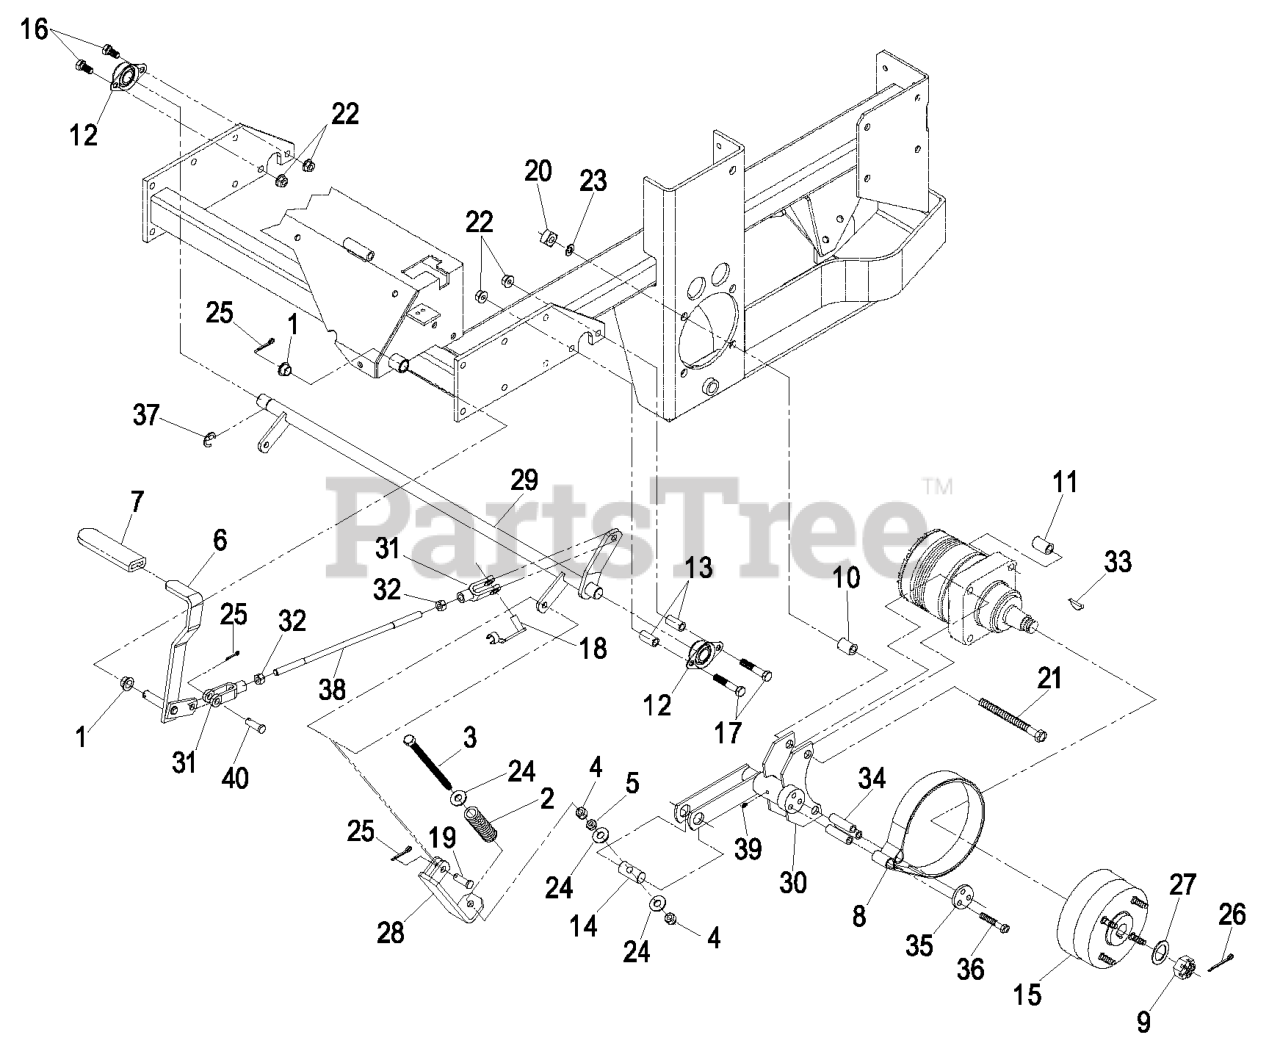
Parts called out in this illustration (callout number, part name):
1	BEARING-CONTROL
2	SPRING-BRAKE
3	BOLT-TAP, HH
4	NUT-LOCK, NI
5	NUT-JAM
6	BRAKE LEVER AND GRIP ASM
7	GRIP-LEVER
10	SPACER-WHEEL, SHORT
11	SPACER-WHEEL, LONG
12	BEARING-FLANGE, SIDE
13	SPACER-RETAINER, BRAKE
14	PIN-TRUNION
15	WHEEL HUB ASM
16	SCREW-HH
17	SCREW-HH
18	PIN-SPRING, CLEVIS
19	PIN-CLEVIS
21	SCREW-HH
22	NUT-HHF, WHIZ
23	WASHER-LOCK
24	WASHER-FLAT
25	PIN-COTTER
26	PIN-COTTER
27	WASHER-SPACER
28	LINKAGE-BRAKE, LOWER
29	SHAFT-BRAKE
30	BRAKE-WIDE
31	YOKE-LINKAGE, BRAKE
32	NUT-HEX
33	KEY-WOODRUFF
35	RETAINER-BAND, BRAKE
36	SCREW-HH
38	ROD-BRAKE
39	FITTING-GREASE
40	PIN-CLEVIS
